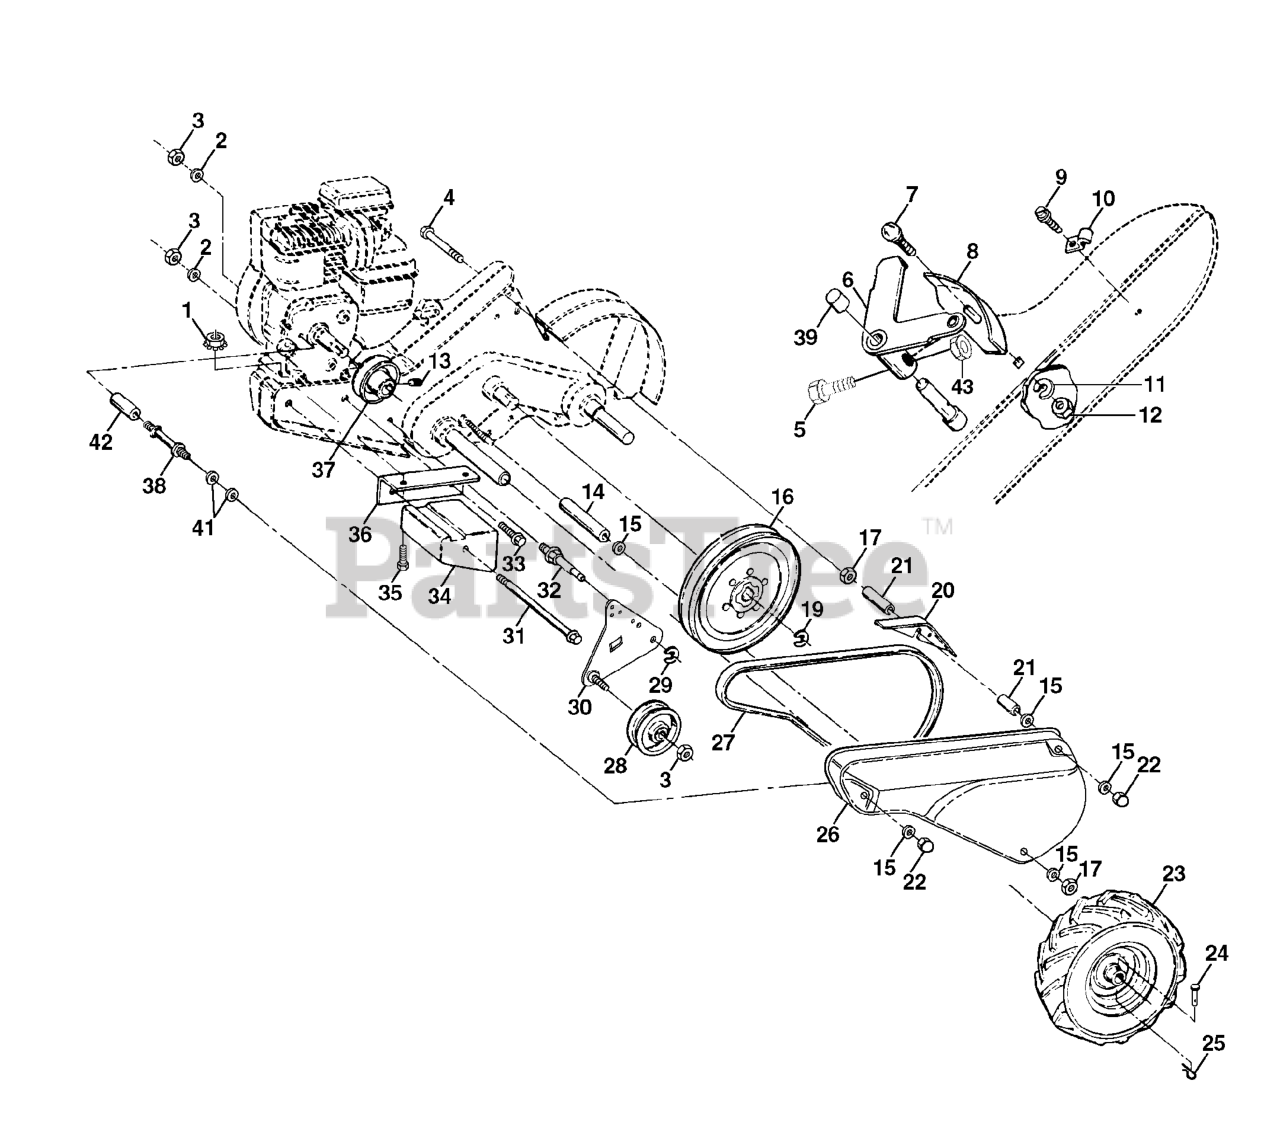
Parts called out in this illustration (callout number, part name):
1	NUT
2	WASHER, LOCK 3/8
3	NUT.HEX.3/8-16UNC
4	Bolt, Hex 5/16-18 x 4-1/4
5	SCREW, SHIFT LEVER
6	LEVER ASM CRT
8	PANEL.INDICATOR.SHIFT.BLACK
9	TAPPING SCREW
10	CONDUIT.CLIP.PLATED
11	LOCKWASHER
12	NUT
15	WASHER
16	SHEAVE, TRANSMISSION
17	NUT
19	RETAINING RING LT
21	SPACER, SPLIT
23	TIRE.16X4-8.CHEVRON.TILLER
23	RIM
23	VALVE STEM LT
24	RIVET,DRILLED
25	RETAINER M
26	BELT GUARD
27	V-BELT
28	PULLEY-IDLER TI
30	BRACKET ASSY TI
31	BOLT.FIN.HEX.3/8-16UNC
32	SHIFT ARM CRT
33	BOLT
34	COUNTERWEIGHT.LH.CRT
35	Bolt, Hex 5/16-18 x 2
36	BRACKET LH CRT
37	RP.ENGINE PULLEY
38	BELT GUARD STUD
39	CAP.PLUNGER.BLACK
